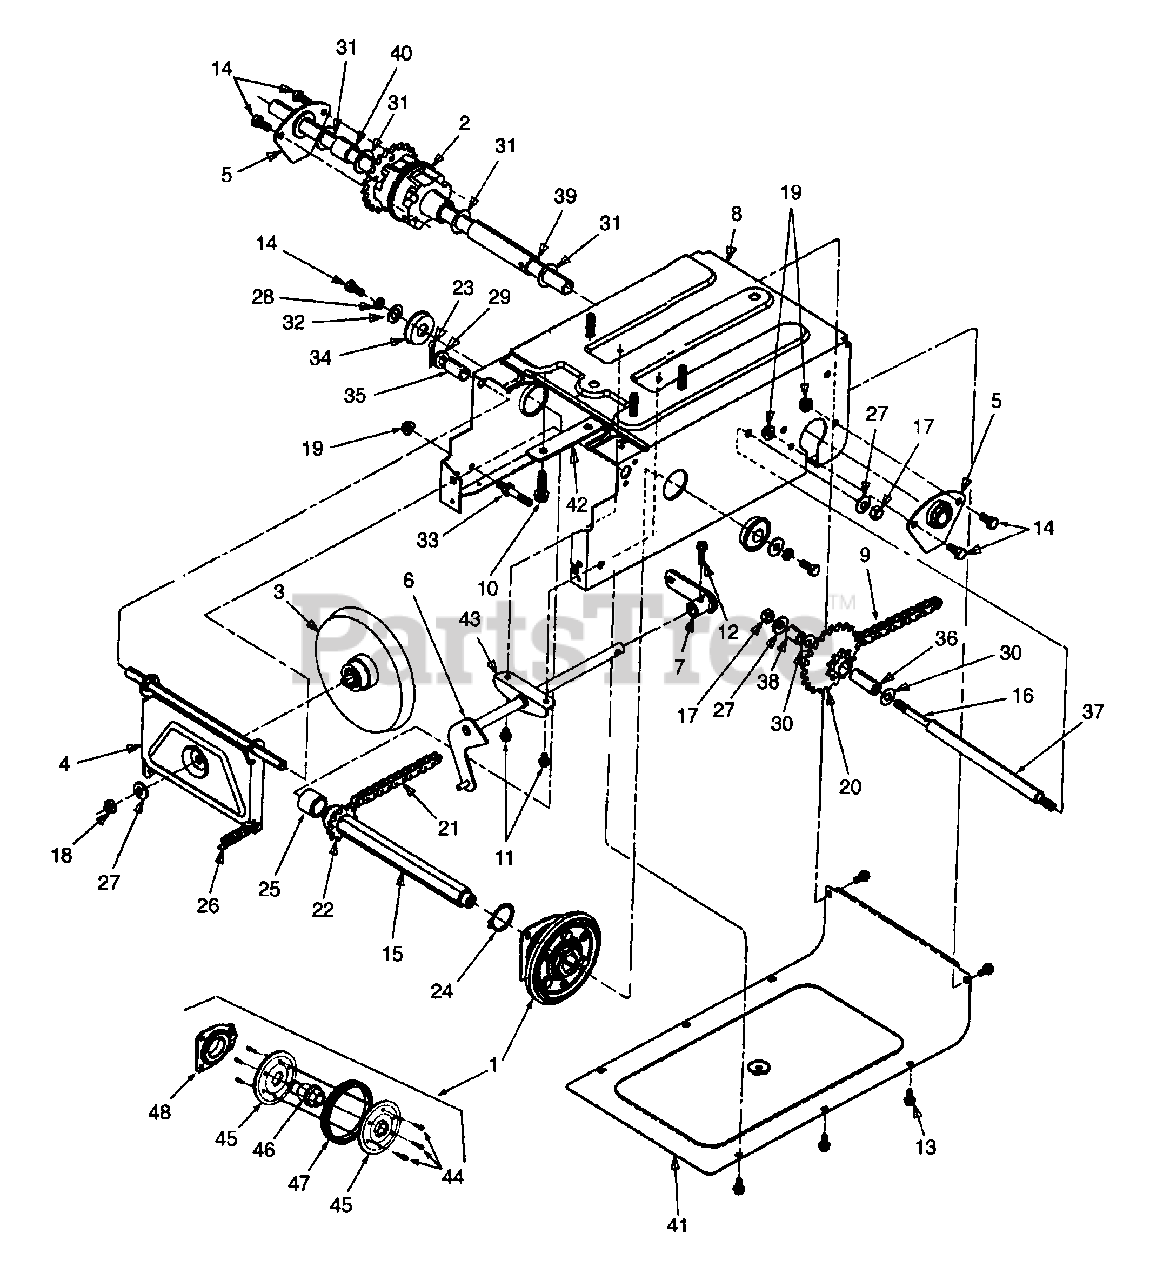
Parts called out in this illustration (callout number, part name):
1	Friction Wheel Ass'y Complete
2	Differential Ass'y Complete
3	Friction Disc Assembly
4	Bracket Ass'y, Frctn Wheel Supt
5	Bracket Ass'y, Axle
6	Shaft Ass'y, Shift
9	Chain, #420 x 36 Lnks
10	Screw, Hex Wash Hd Tapp 3/8-16 x 1.25
11	Screw, Hex Wash Hd Tapp 1/4-20 x .375
12	Screw, Hex Wash Hd Tapp 1/4-20 x 10
13	Screw, Hex Wash Hd Tapp 1/4-14 x .625
14	Screw, Hex Cap, 5/16-18 x .75 GR5
15	Hex Shaft
16	Jack Shaft
17	Nut, Hex, 3/8-24
18	Nut, Hex Jam, 3/8-24
19	Nut, Hex Flange Lock, 5/16-18 GR5
20	Sprocket Ass'y, 9T & 22T
21	Chain, #41 x 36 Lnks
22	Sprocket, 107
23	Pin, Cotter, 3/32 x 1.0
24	Ring, Snap, 1.0 Dia
25	Spacer, .675 x 1.0 x 1.53
26	Spring, Extension
27	Washer, Bell, .406 x .870 x .063
28	Washer, Lock, 5/16
29	Washer, Flat, .536 x .930 x .05
30	Washer, Flat, .385 x .87 x .06
31	Washer, Flat, .793 x 1.24 x .06
32	Washer, Flat, .345 x 1.0 x .100
33	Bolt, Idler
34	Bearing, Ball
35	Spacer, .508 x .75 x .94
36	Sleeve, .380 x .623 x 1.5
37	Spacer, .407 x .625 x 7.86
38	Spacer, .407 x .625 x .71
39	Spacer, .782 x 1.0 x 4.11
40	Spacer, .782 x 1.0 x .99
41	Cover, Frame Bottom
44	Screw, Hex Wash Hd Tapp 1/4-20
45	Plate, Friction Wheel
46	Hub, Friction Wheel
47	Wheel, Rubber Friction
48	Bearing Ass'y, Friction Wheel
